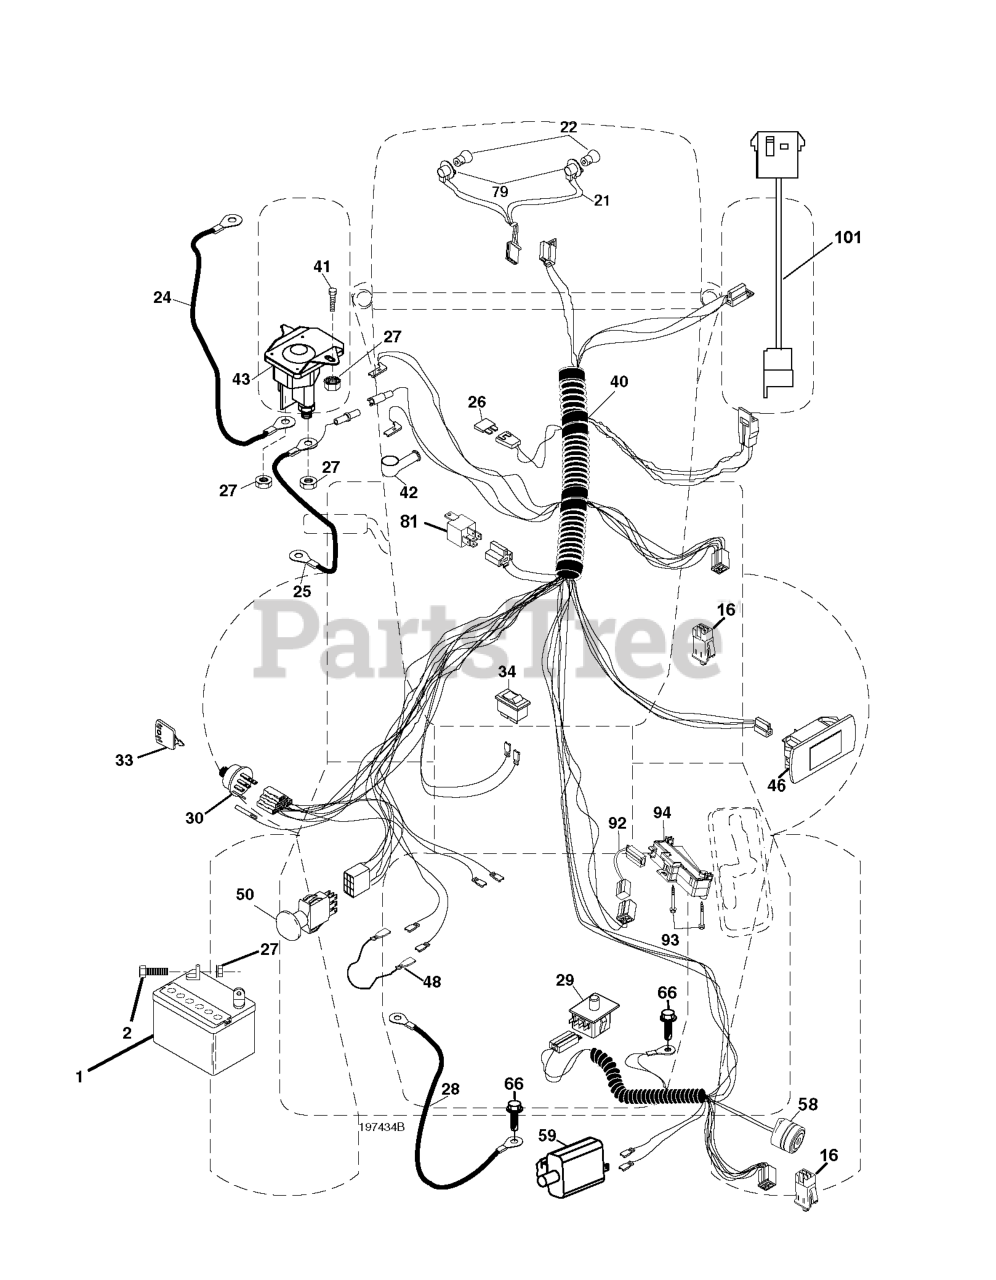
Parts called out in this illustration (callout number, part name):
1	BATTERY 12V .35 AMP
2	BOLT.HEX.1/4.X.3/4.DICHROMATE
16	SWITCH INTERLOOK PUSH-IN
21	HARNESS.LIGHT W/4152J BULBS
24	BATTERY CABLE GT
25	CABLE BATTERY
26	FUSE 20AMP
27	NUT
28	CABLE GROUND
29	SWITCH.SEAT.DP W/RAMPS
30	SWITCH.IGN.DELTA.W.LGH.ROS
33	KEY MLD GEN DELTA
40	RP HARNESS.IGN.ELECT.REG.CRD
41	BOLT
42	TERMINAL COVER
43	SOLENOID.W/BRASS.PLUNGER
46	RP.GUAGE.SRVCMNDR.HRMTR.
48	ADAPTER.AMMETER
50	RP.PTO.SWITCH.8 TERMINAL.BLACK
58	BUZZER
59	.WITCH.FULL BAGGER.INDICATOR
79	BULB HOLDER ASM.
81	RELAY.ASSY.T
92	HARNESS.PIGTAIL.CONSLE
93	SCREW.PLASTITE
94	MODULE.REVERSE.ROS
101	PIGTAIL.MATNLK.NEW.HAR
